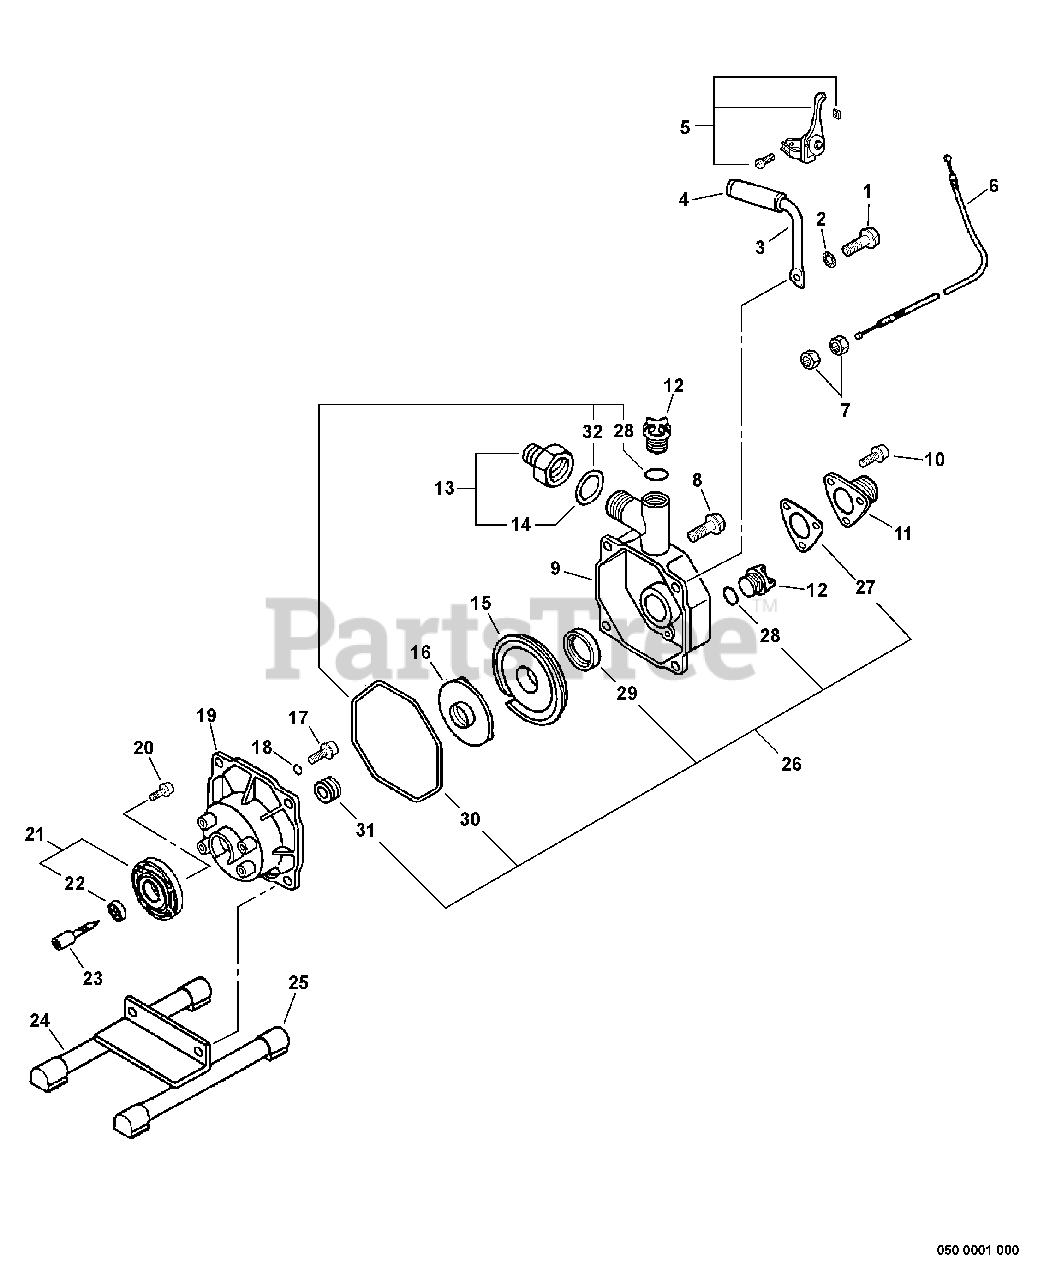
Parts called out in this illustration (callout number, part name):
1	BOLT - 8X35 -- TAPPING
2	LOCKWASHER - 8
4	GRIP, HANDLE - REAR
5	THROTTLE CONTROL KIT
6	CABLE, THROTTLE
8	BOLT - 8X25 -- TAPPING
9	CASE, PUMP
10	BOLT - 6X20
11	CASE, CHECK VALVE
12	PLUG
13	NIPPLE - 1 X 3/4"
15	CASE, IMPELLER
16	IMPELLER
17	SCREW - 5X25
19	CASE, PUMP
20	SCREW - 5X25
21	PUMP ADAPTOR ASSY
22	BEARING, BALL - 6201
23	SHAFT, PUMP
24	FRAME, PUMP
26	PUMP REBUILD KIT
27	VALVE, CHECK
28	O-RING - 24
29	GASKET, PUMP
